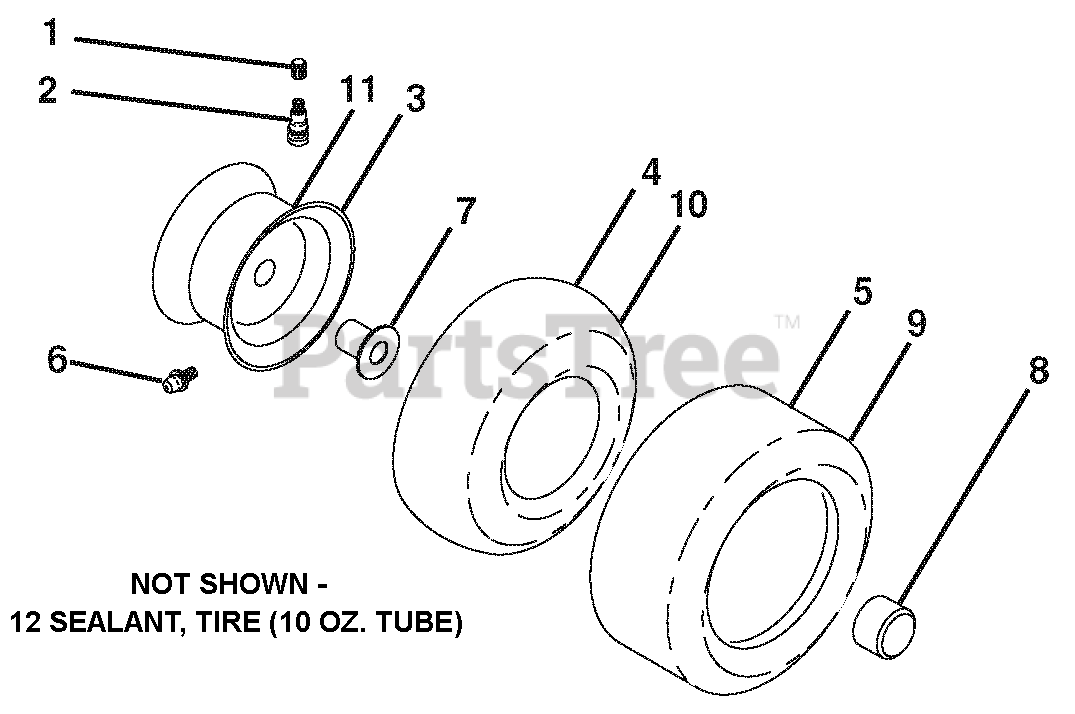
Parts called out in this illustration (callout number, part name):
1	CAP.VALVE.TIRE
2	STEM.VALVE
3	RIM.ASM.6"FRONT .643
4	TUBE.INNER.FRONT.#35060
5	TIRE.F.TS.15 X 6.0 - 6.SERVICE
6	FITTING.GREASE
7	BEARING.FLANGE
8	CAP.HUB.AXLE.W.GRY.1.50 X 1.00
9	TIRE.R.TS-LT.18X9.5-8.C.SERV.
10	TUBE.REAR.9.5 X 8.SERVICE
11	RIM ASM.8"REAR.W.GRY.SRVCE.643
12	SEALANT, TIRE (10 OZ. TUBE)
